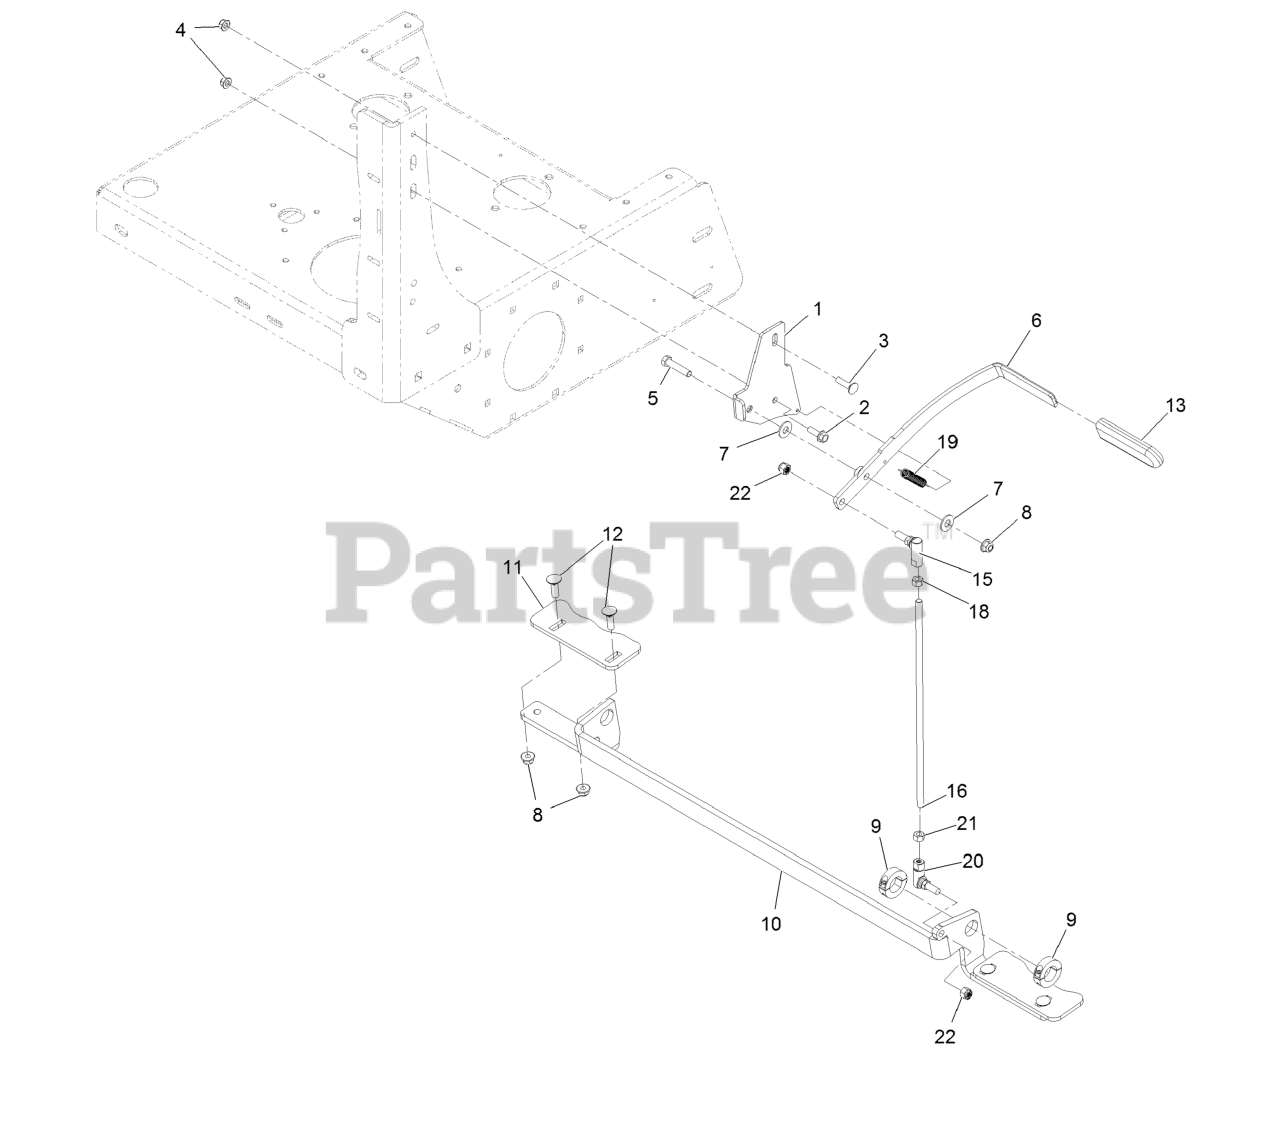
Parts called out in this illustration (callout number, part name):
1	PLATE-BRAKE
2	SCREW-HH
3	Bolt-Carriage 5/16-18 X 1 1/4
4	NUT-HF, NI
5	SCREW-HH
6	HANDLE-BRAKE
7	WASHER-PLAIN
8	NUT-HF, NI
9	COLLAR-LOCKING
10	PIVOT-BRAKE, ROD
11	PAD-BRAKE
12	Bolt-Carriage 3/8-16 X 1 1/4
13	GRIP-LEVER
15	BALL JOINT-SS
16	BRAKE ROD 14.5"
18	NUT-HEX
19	SPRING-EXTENSION
20	BALL JOINT-SS
21	NUT-HEX, LH
22	XREF 126-4803
